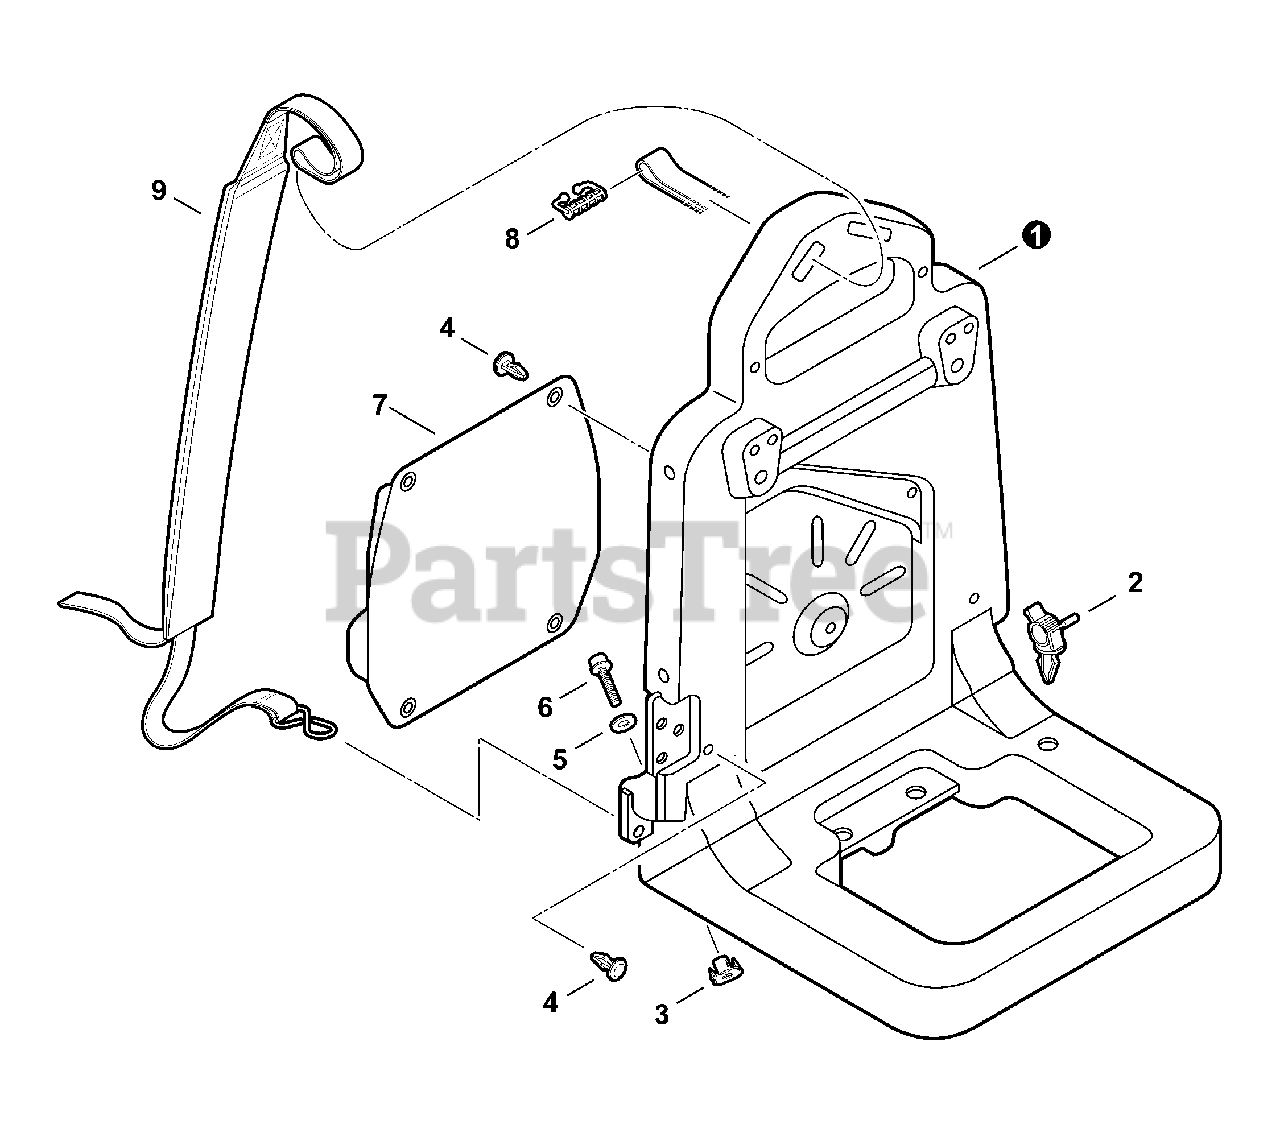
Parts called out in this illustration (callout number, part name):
1	FRAME, BACKPACK
2	CLIP, CABLE
5	WASHER 6.6×20×1.6
6	BOLT 6×25
7	CUSHION, BACKPACK
8	CLIP, HARNESS
9	HARNESS ASSY, BACKPACK
